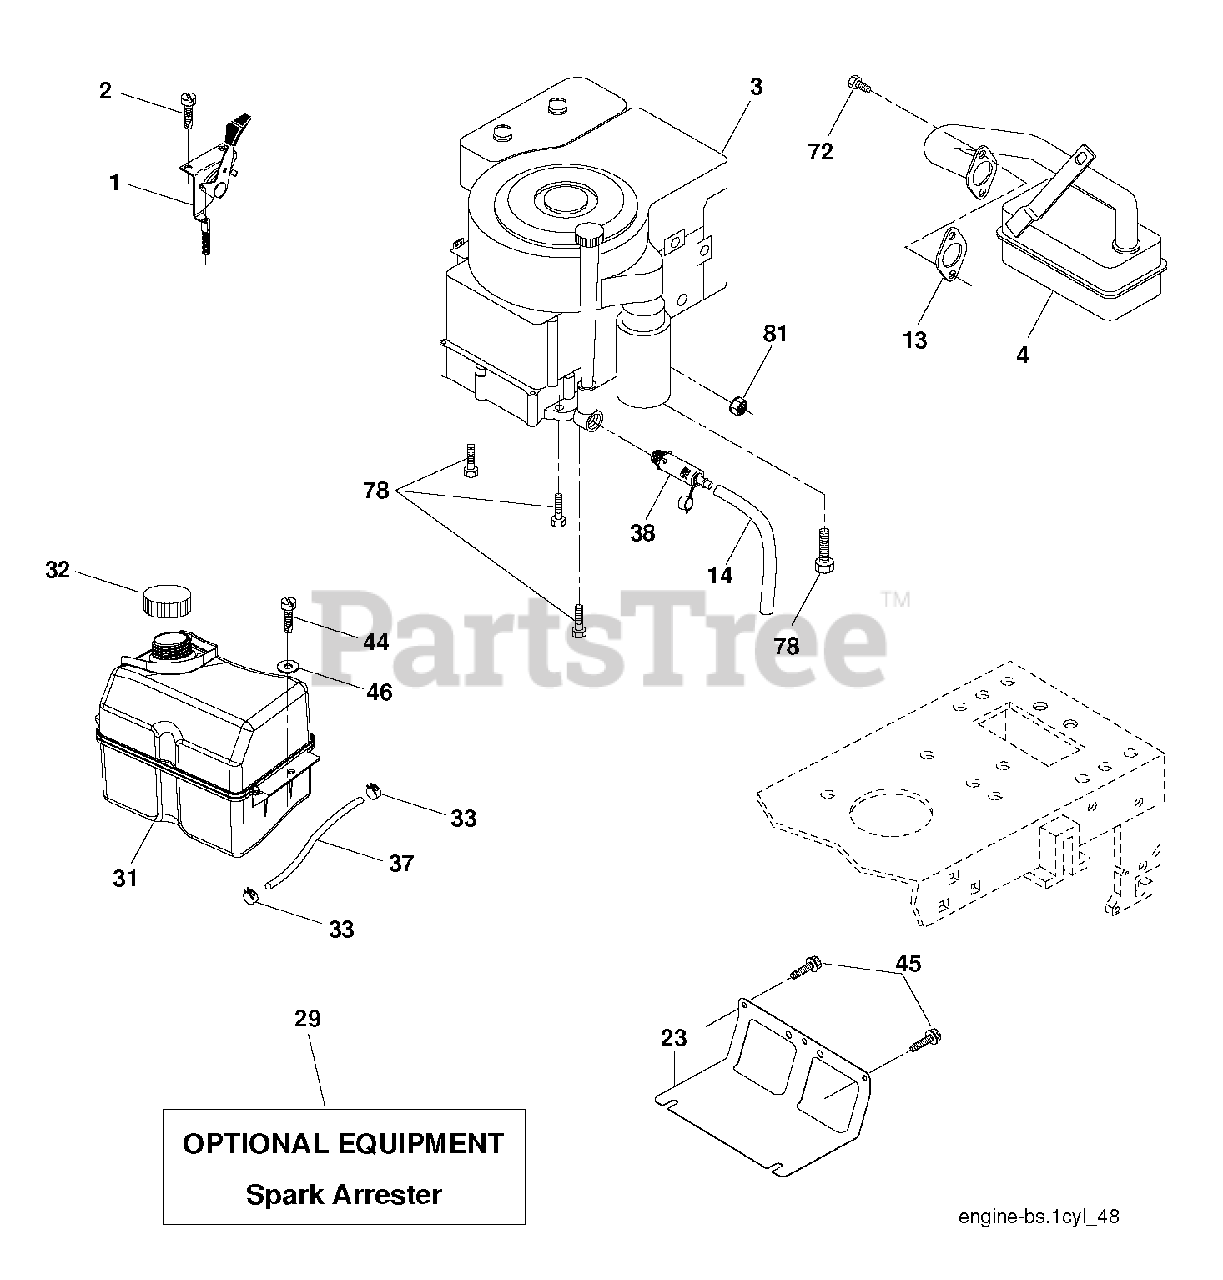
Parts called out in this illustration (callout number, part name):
1	CONTROL.TH/CK.C.
2	SCREW
13	REPL BY 532 27 22-93
14	TUBE, DRAIN OIL ASM.
23	SHEILD.BROWNING.DBR.GUARD
29	ARRESTER SPARK (OPTIONAL)
31	FUEL TANK FRT 2 GAL.
32	FUEL CAP
33	HOSE CLAMP
37	LINE.FUEL.20
38	PLUG DRAIN OIL EASY
44	SCREW HEXWSHR 1/4-20X3/4
45	SCREW, 3/8-16X3/4
72	SCREW.SOCKET HD.5/16-1
78	SCREW.3/8-16
81	NUT
